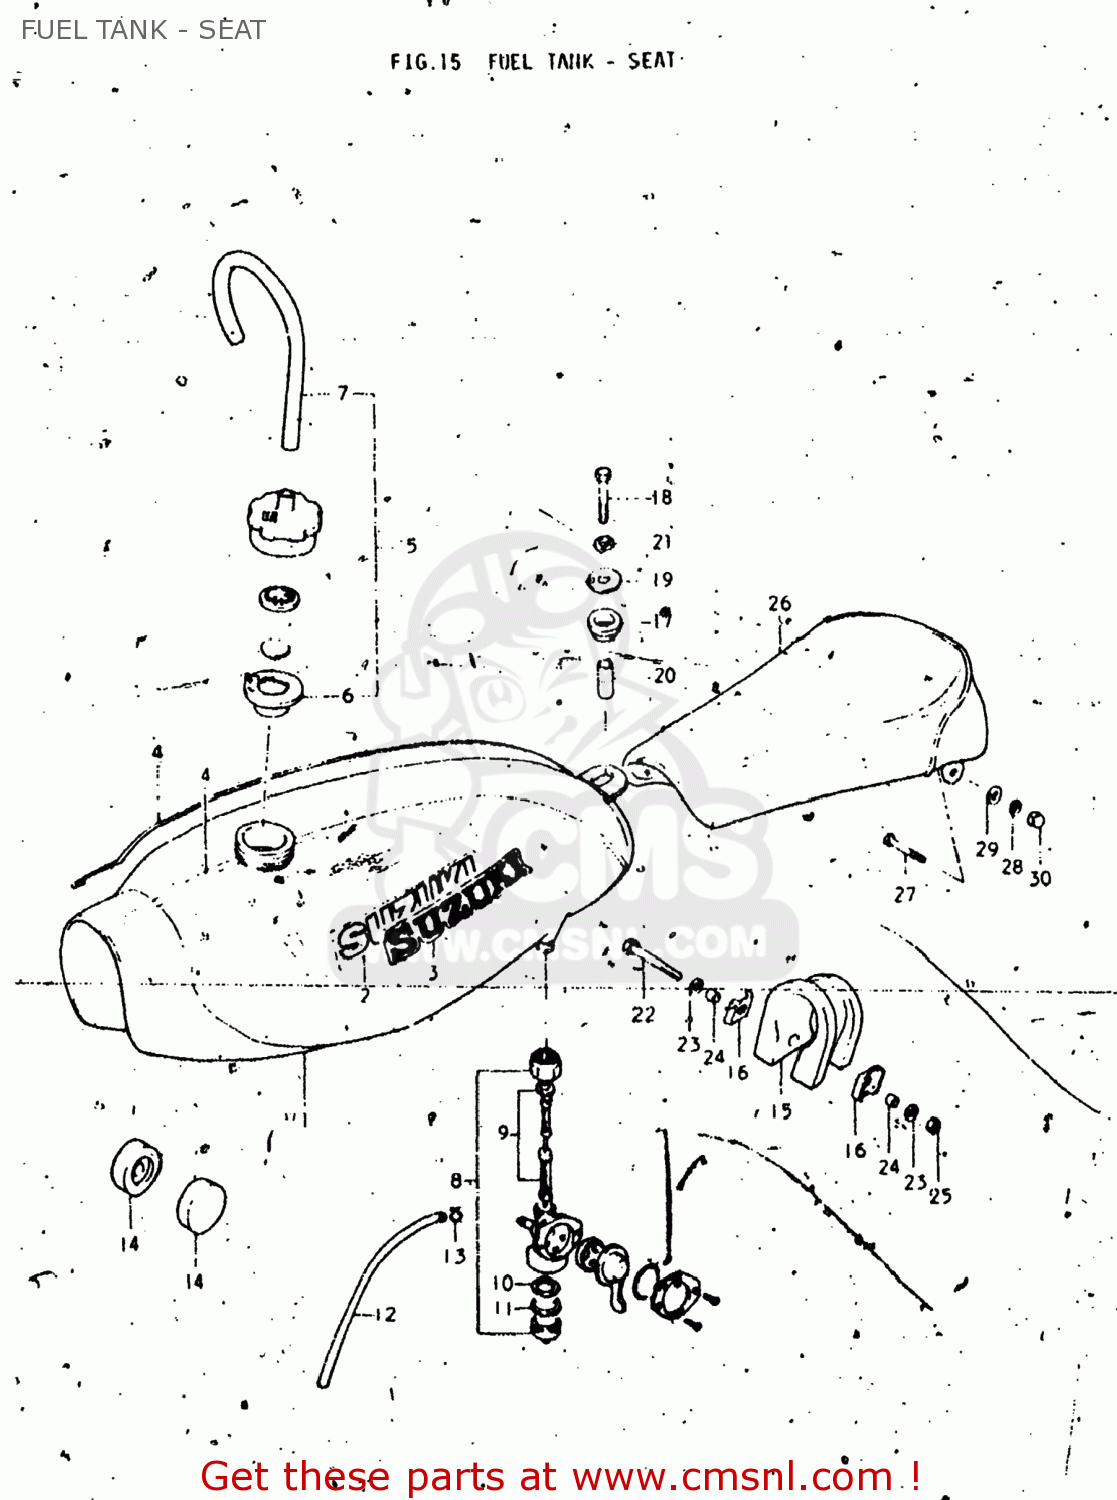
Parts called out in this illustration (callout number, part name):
1	TANK ASSEMBLY,FUEL
2	EMBLEM
3	EMBLEM
4	TAPE,FUEL TANK
5	CAP ASSY,FUEL TANK FILLER
6	GASKET,FUEL TANK CAP (NAS)
7	HOSE
8	COCK ASSEMBLY,FUEL
9	FILTER SET,FUEL
10	NET,STRAINER
11	GASKET,STRAINER CUP (NAS)
12	HOSE
13	CLIP
14	CUSHION
15	CUSHION,FUEL TANK,REAR
16	CLIP
17	CUSHION
18	BOLT 8X40
19	WASHER (8.5X24X2.3)
20	SPACER
21	LOCK WASHER
22	BOLT
23	WASHER 6MM
24	SPACER (6.1X8X5.2)
25	NUT
26	SEAT ASSEMBLY
27	BOLT
28	LOCK WASHER
29	WASHER
30	NUT
